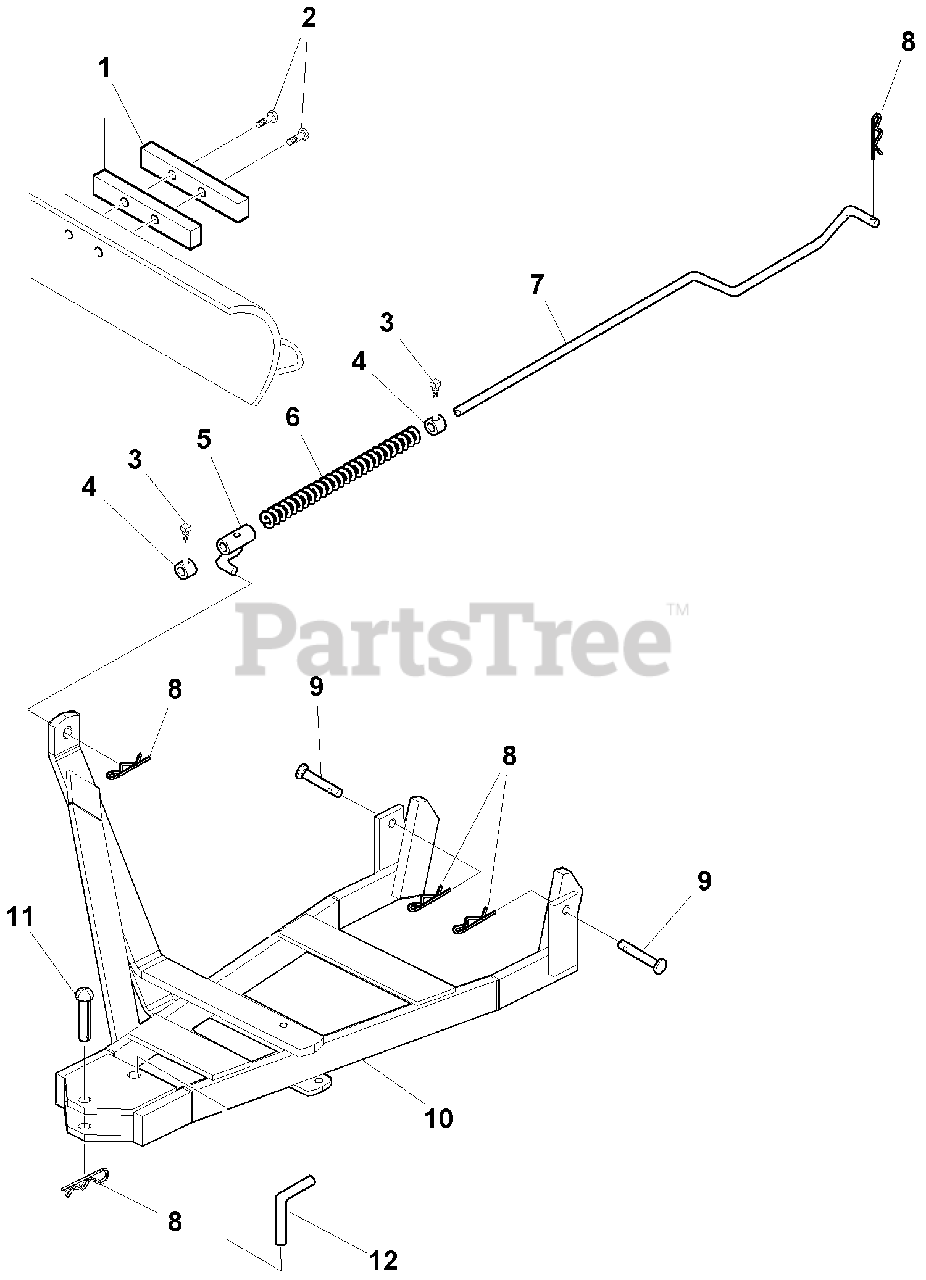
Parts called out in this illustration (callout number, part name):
1	BAR
2	CAPSCREW, Taptite, 5/16-18 x 1
3	SCREW, Set, 5/16-18 x 1/2
4	COLLAR
5	GUIDE ASSEMBLY
9	PIN
10	PUSH BAR ASSEMBLY
